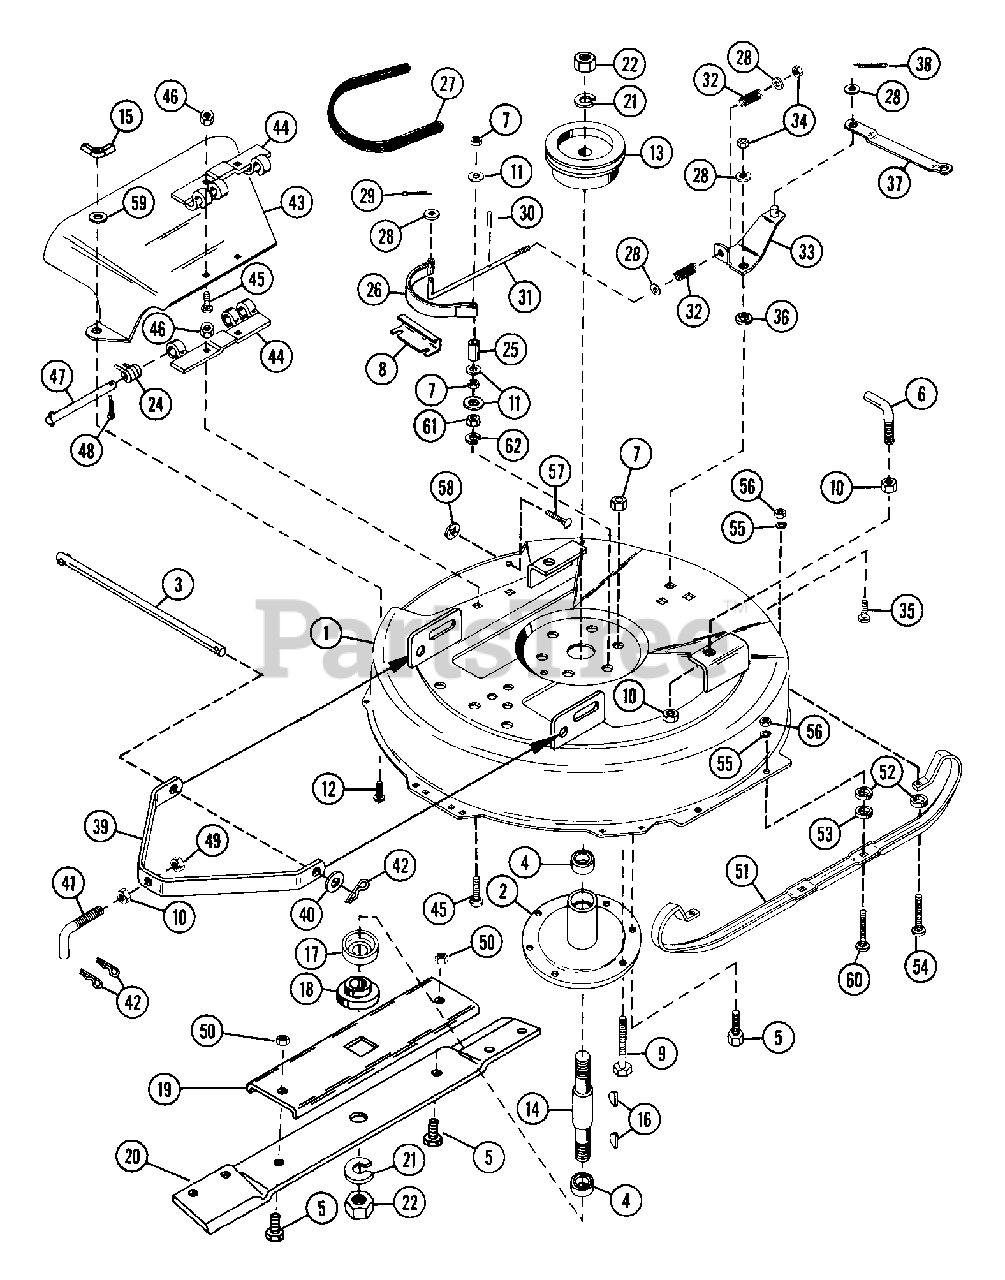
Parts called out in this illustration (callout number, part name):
1	32 IN MOWER PAN SERVICE ASSEMB
2	SPINDLE HOUSING
3	TOW PIN
4	BRG-BALL .750X1.781X.61
5	BLT-HEX .38-16X1.00 PL GR5
6	HANGER HOOK
7	NUT-LK-CTR .375-16 GR A PL
8	BRAKE BAND SUPPORT
9	BLT-HEX .38-16X3.00 PL GR5
10	NUT-JAM .50-13 PL
11	WSHR-FL-STL.406X.812X.065PL
12	BLT-RDHDSQNK .31-18X.75 GR5 PL
13	MOWER SHEAVE
14	SPINDLE SHAFT
15	NUT-WING W/INSERT .312 - 18
16	KEY-WDRF .188X.75X.313 SAE 9
17	BEARING SLINGER
18	RETAINER HUB
19	BLADE TRAY
20	MOWER BLADE 32
21	WSHR-LK .750X.188 MED PL
22	NUT-JAM .75-10 PL
23	NUT-LK-NYL .375-16 PL
24	SG-TORS .090X.37X.63
25	SPACER .386X.502X1.060
26	BRAKE BAND
27	V-BELT, 4L-RAW EDGE
28	WSHR-FL-STL .323X.625X.062 PL
29	PIN-COTR .06X.50
30	PIN-ROLL .125X1.00
31	BRAKE ROD
32	SG-COMP .057X.47X1.25
33	BRAKE ACTUATOR
34	NUT-LK .312-18 GR A PL
35	BLT-HEX .31-18X.75 PL GR5
36	SPACER -FLANGED .325X.498X.318
38	PIN-COTR .12X1.0 PL
39	MOWER STRAP
40	WSHR-FL-STL .505X.880X.072 PL
42	PIN-HAIR INT .09X.188 PL
43	CHUTE DEFLECTOR W/ DECAL
44	HINGE PLATE
45	BLT-RDHDSQNK .25-20X.62 PL
46	NUT-LK-CTR .250-20 PL
47	CLEVIS PIN
48	PIN-COTR .09X.75 PL
49	NUT-LK-CTR .50-13
50	NUT-LK TOP .375-16 GR C YWZC
51	32 IN ADJUSTABLE SKID
52	SPACER .328X.750X.375
53	SPACER BUSHING .5 X .32 X .21
54	BLT-RDHDSQNK .31-18X1.75 SHTPL
55	WSHR-LK .312X.097 PL HVY
56	NUT-HEX .312-18
57	BLT-RDHDSQNK .38-16X1.75 PL
58	NUT-PUSH .312
59	WSHR-FL-STL .328X.875X.062 PL
60	BLT-RDHDSQNK .31-18X1.25 SHTPL
61	NUT-HEX .375-16
62	WSHR-LK .375X.115 HVY PL
